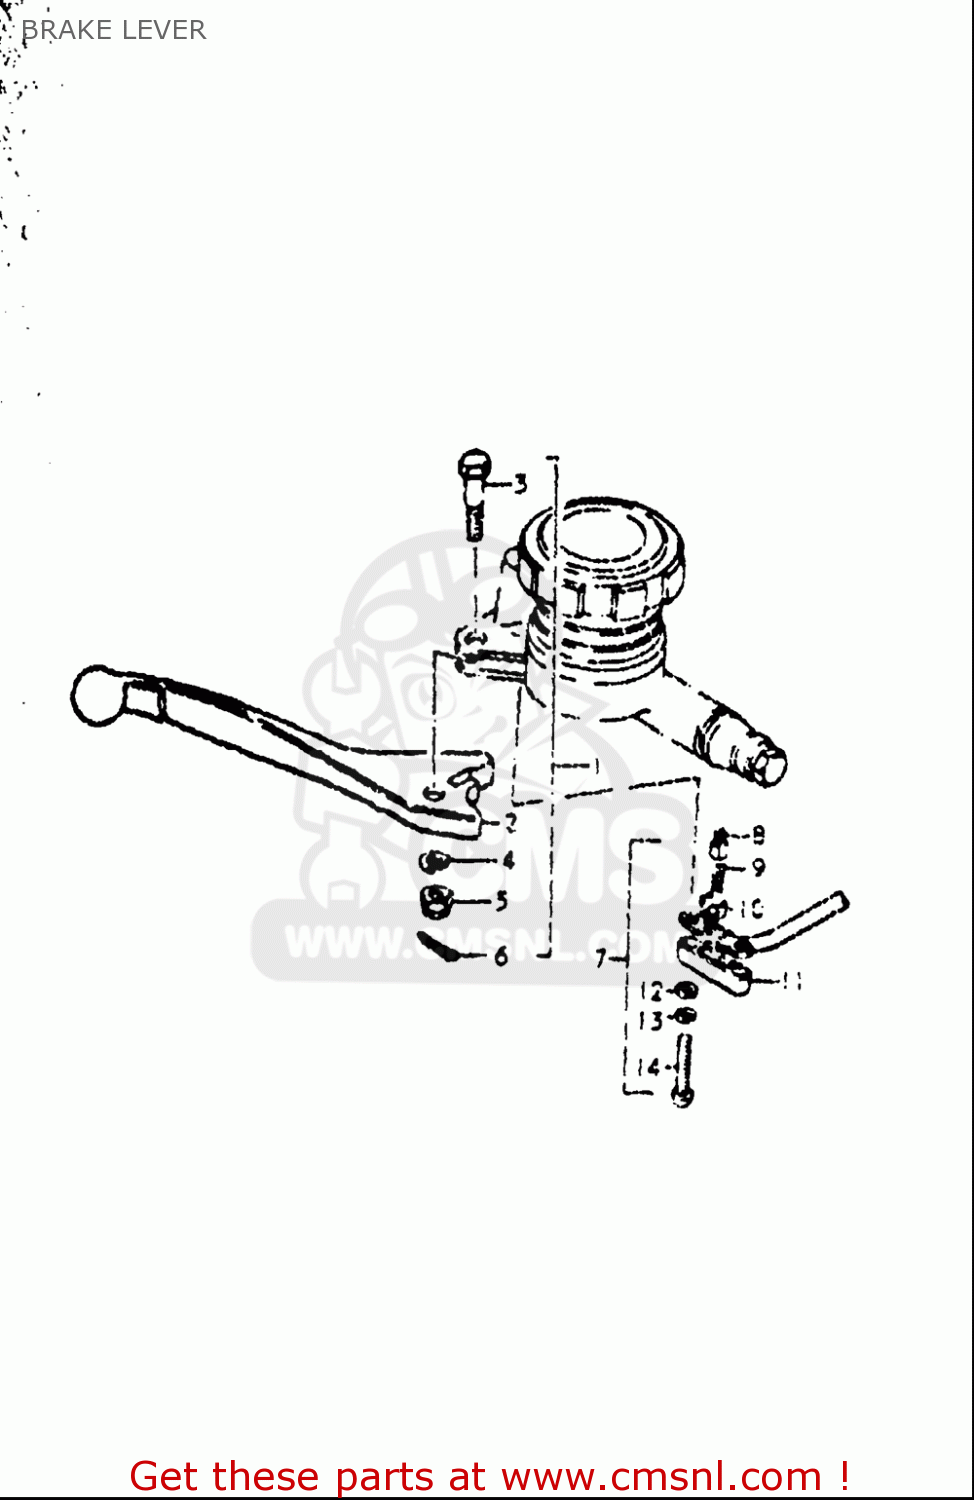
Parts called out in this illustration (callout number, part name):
2	LEVER,BRAKE
3	BOLT
4	WASHER,LOCK
5	NUT,LEVER FITTNG
7	SWITCH ASSY,STOP
8	CONTACT,SWITCH
9	CONTACT,SWITCH
10	CONTACT,SWITCH
11	COVER,FR BK TERMINAL BASE
12	WASHER
13	WASHER,LOCK
14	SCREW
